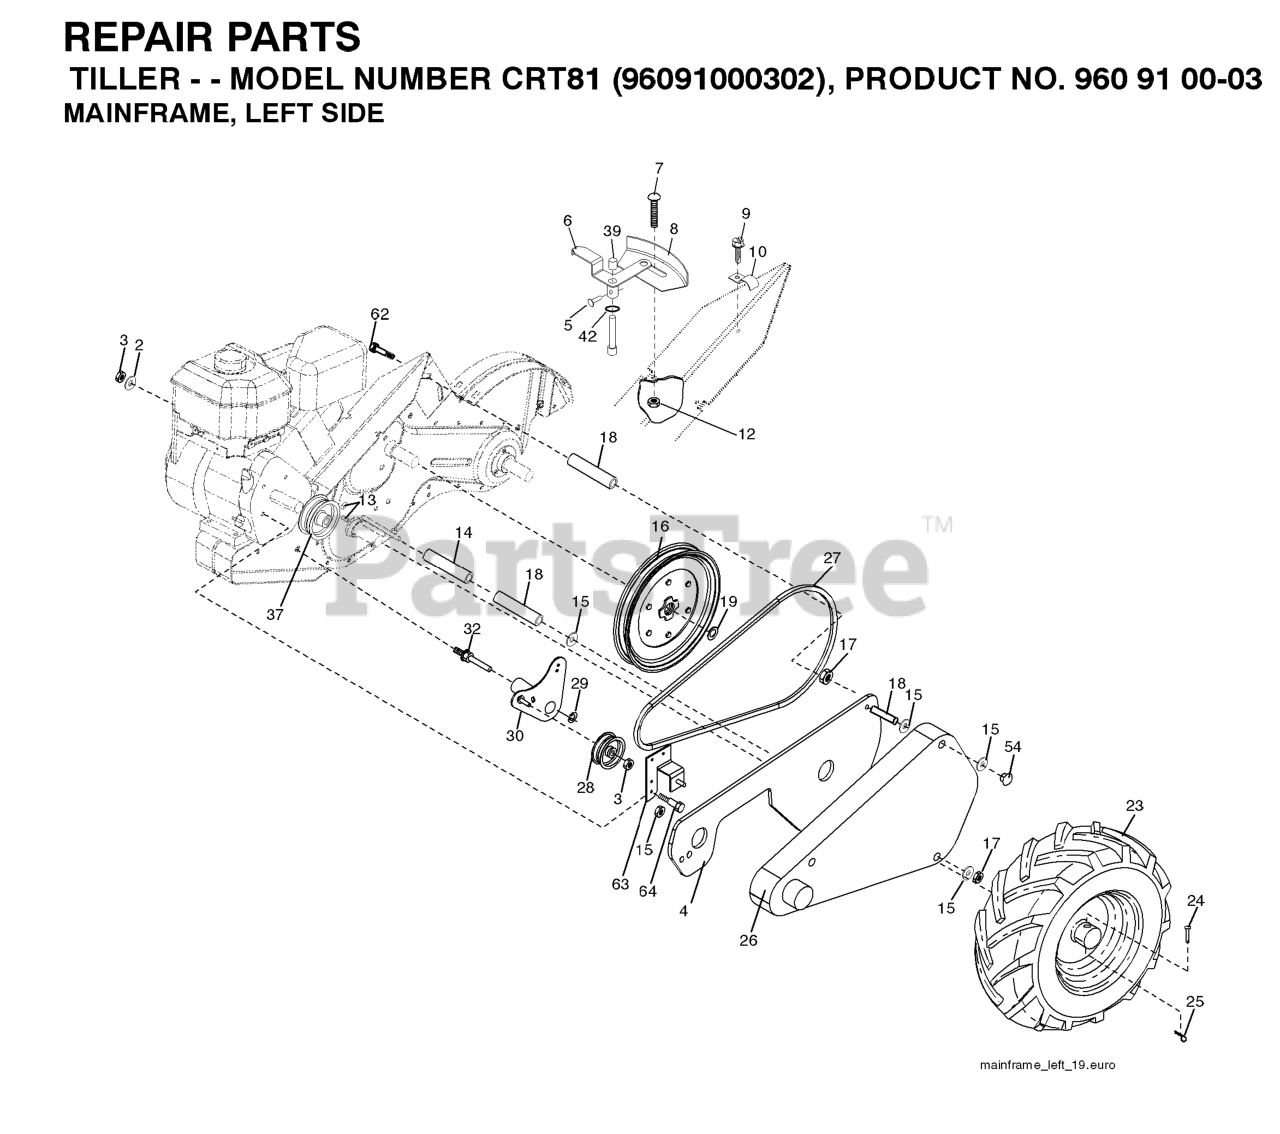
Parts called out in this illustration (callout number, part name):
2	WASHER, LOCK 3/8
3	NUT.HEX.3/8-16UNC
4	Shield, Inner Belt Guard RT
5	PIN.SPIROL.FLARED
6	LEVER ASM CRT
8	PANEL.INDICATOR.SHIFT.BLACK
9	TAPPING SCREW
10	CONDUIT.CLIP.PLATED
12	NUT
14	SPACER-SPLIT.327 X .42
15	WASHER
16	SHEAVE, TRANSMISSION
18	SPACER SPLIT
19	RETAINING RING LT
23	TIRE.16X4-8.CHEVRON.TILLER
25	SPRING TI
26	FOOTREST.PNT.LH
27	BELT, DRIVE
28	PULLEY-IDLER TI
30	BRACKET.ASM.IDLER.BLACK
32	SHAFT, IDLER ARM
37	SHEAVE, ENGINE
39	CAP.PLUNGER.BLACK
47	KEY, SQUARE
62	BOLT 5/16-18X4 1/2
63	Bracket Asm Guard
